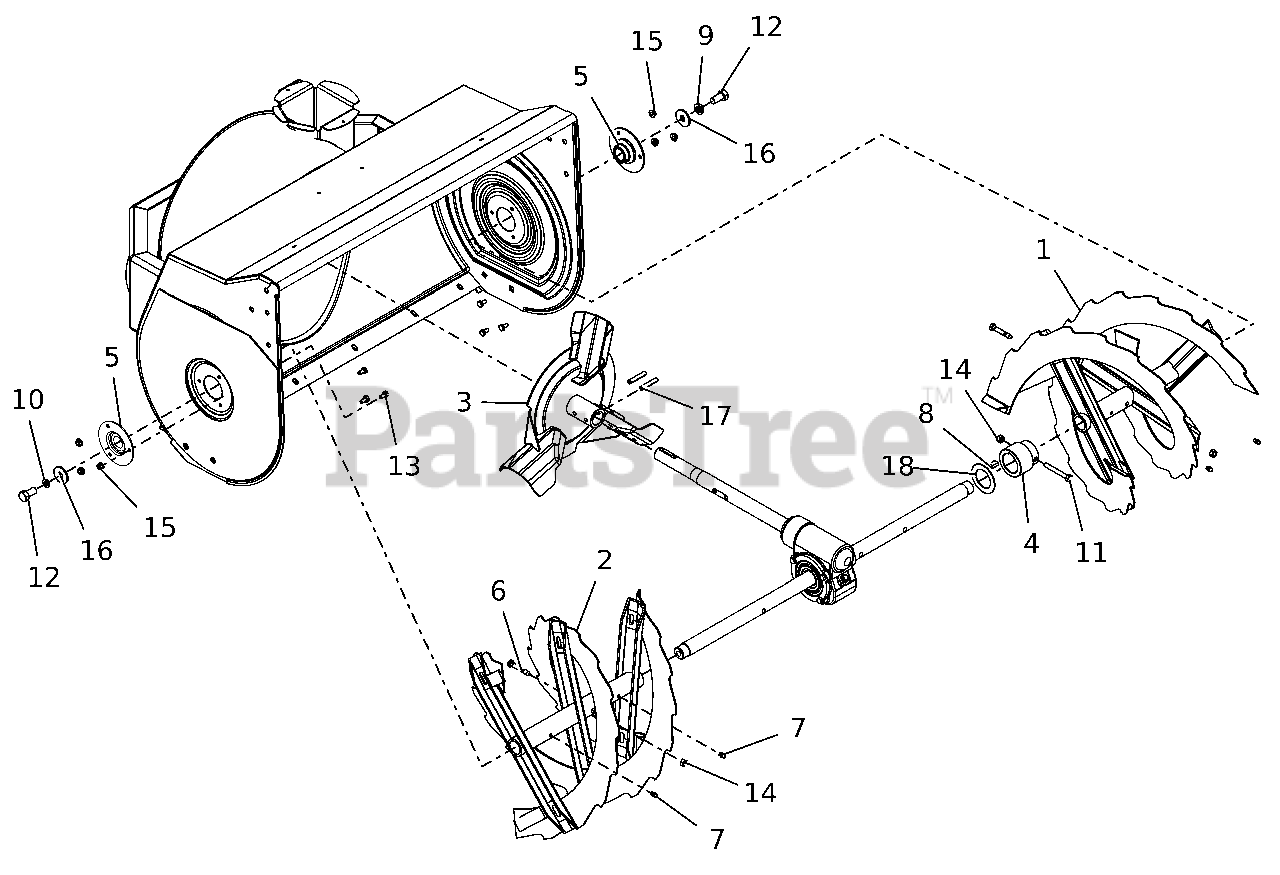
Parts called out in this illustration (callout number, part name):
1	RAKE, L.H.-32" (1.12 X 16)
2	RAKE, R.H.-32" (1.12 X 16)
3	IMPELLER, 3 BLADE 16"
4	ADAPTER, RAKE SHAFT
5	ASSY, FLANGE BEARING
6	SHEAR BOLT & NUT ASSEMBLY
7	FTG-LUBE .25-28X.256 SST
8	KEY-SQ .25X.625X.375
9	WSHR,LK-HVY .500X.151 ZCC
10	WSHR,LK-REG .375X.094 ZCC
11	BLT,HEX .31-18X2.50 G8 ZCC
12	BLT, HEX .50-13X1.00 G5 ZCC
13	BLT,HEX .25-20X.50 G5 ZCC
14	NUT,LK-CTR .31-18 GA ZCC
15	NUT-SPNLK-FLG .25-20 ZC120
16	WSHR-FL-STL.511X1.44X.125ZC120
17	PIN-ROLL .313X1.75
18	WSHR-FL-NYL 1.625X2.500X.060
